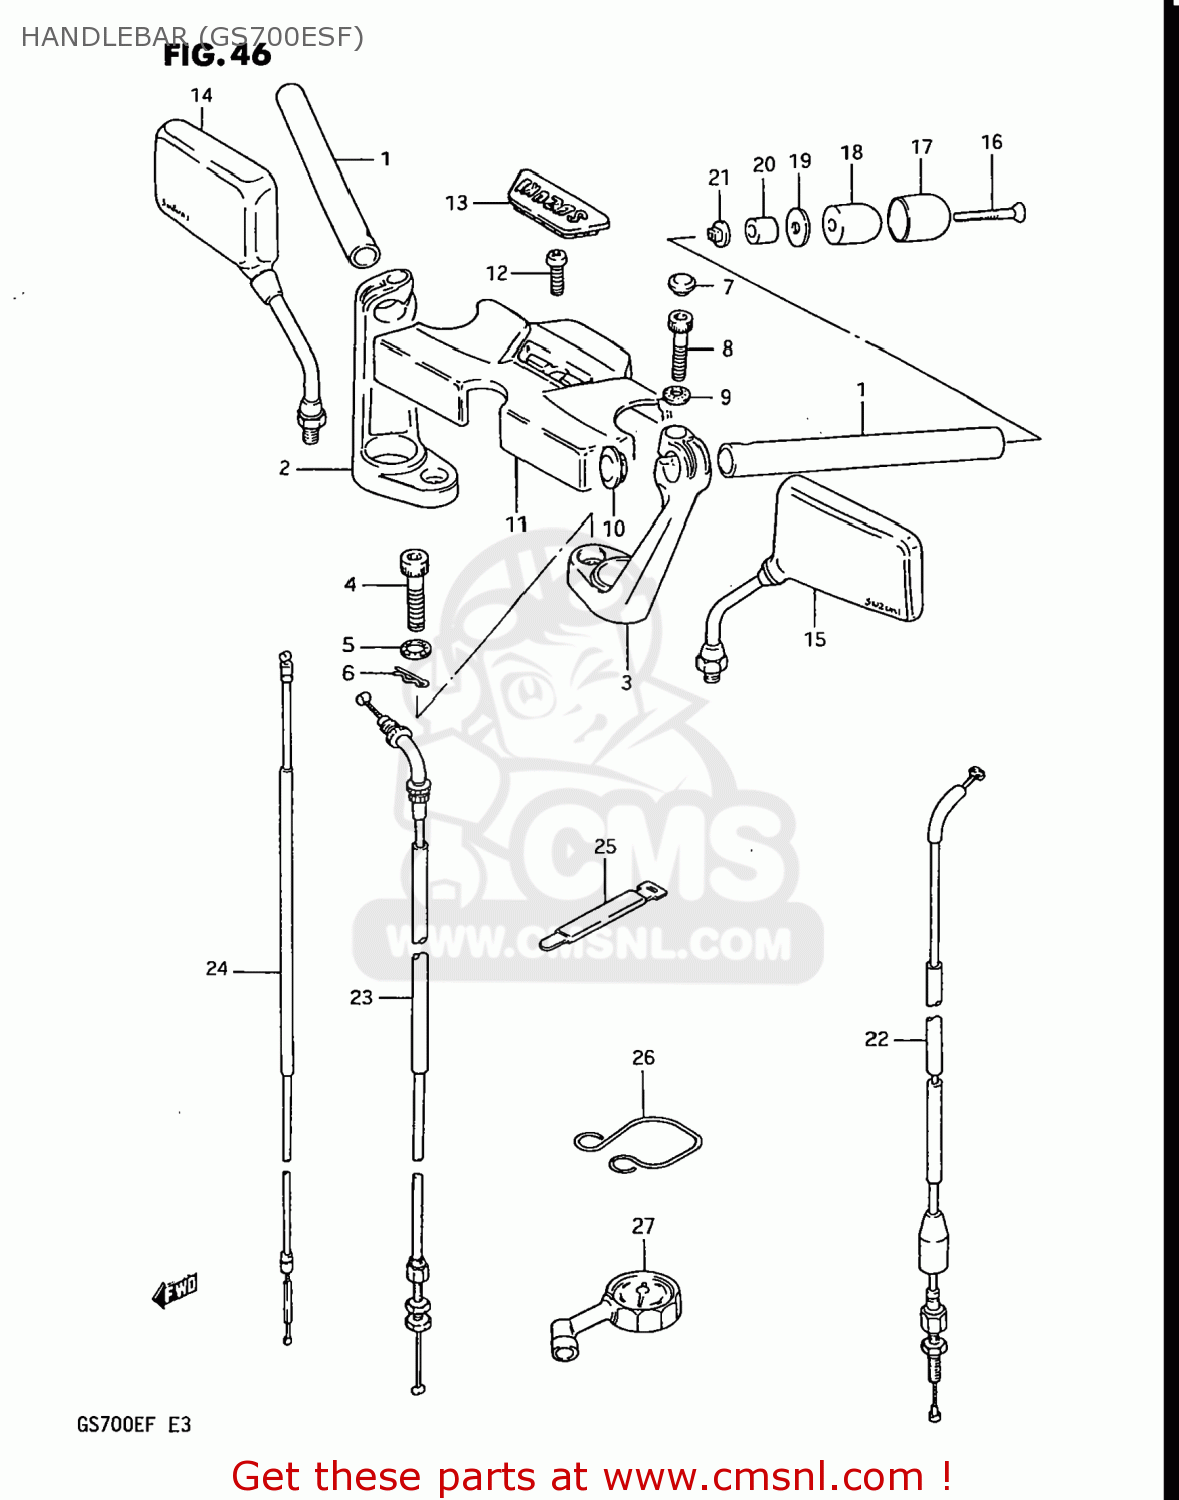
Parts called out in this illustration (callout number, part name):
1	HANDLEBAR
2	HOLDER,HANDLEBAR,RIGHT
3	HOLDER,HANDLEBAR,LEFT
4	BOLT 10X50
5	WASHER
6	CLIP
7	CAP(OD:14.5)
8	BOLT 8X35
9	WASHER
10	CAP,GRIP END
11	PAD,HANDLE
12	SCREW
13	CAP,HANDLE PAD
14	MIRROR ASSEMBLY,RIGHT
15	MIRROR ASSEMBLY,REAR VIEW
16	SCREW 6X65
17	CAP,BALANCER
18	BALANCER,HANDLE
19	SPACER,BALANCER
20	EXPANDER,BALANCER
21	NUT
22	CABLE ASSY,CLUTCH
23	CABLE ASSY,THROTTLE
24	CABLE COMP,STARTER
25	CLAMP
26	GUIDE,CABLE/HARNESS
27	GAUGE ASSY,AIR PRESSURE
